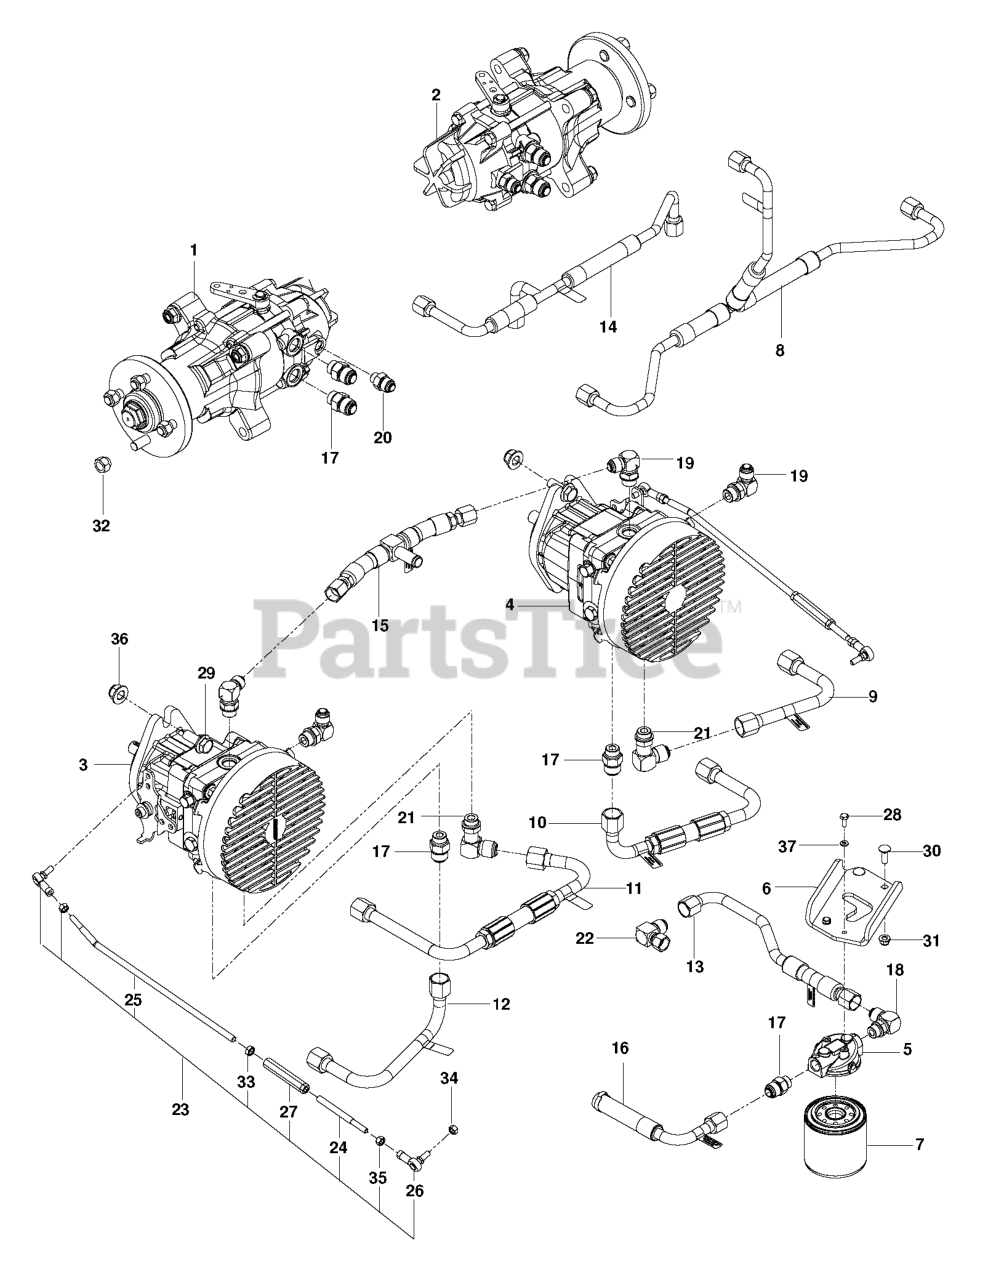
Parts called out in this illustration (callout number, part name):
1	HG_MOTOR, PRM, RT
2	HG_MOTOR, PRM, LT
3	HG_PUMP, 21CC, RT
4	HG_PUMP, 21CC, LT
5	FILTER HEAD
6	MOUNT, FILTER, BLK
7	FILTER 25 MICRON
8	LINE, HYD, CASE-RM
9	LINE, HYD, LT-AA
10	LINE, HYD, LT-BB
11	LINE, HYD, RT-AB
12	LINE, HYD, RT-BA
13	LINE, HYD, SUCTION
14	LINE, HYD, PUMP
15	LINE, HYD, CHARGE
16	LINE, HYD, CHARGE
17	FITTING, 10-8 STRAIGHT
19	ELBOW, 90 DEGREE
20	FITTING, HYDRO
21	FITTING, 10-8 90 DEG
22	FITTING, HYD, 6500-10-8
23	LINKAGE, CONTROL, DIESEL
24	LINKAGE, CONTROL, FT
25	LINKAGE, CONTROL
26	SPHERICAL ROD END, RH
27	TURNBUCKLE, 3/8
28	HCS 1/4C X 5/8
29	HCS 1/2C X 1 1/4 SERRATED HEAD
30	RHSNB 5/16C X 1
31	5/16-18 NYLOC FLANGE NUT
32	LUG NUT 1/2F
33	NUT 3/8-24 JAM
34	NUT 5/16F NYLOC
36	NUT, 1/2-13 HEX FLG NYLOC ZD
37	LOCKWASHER 1/4"
